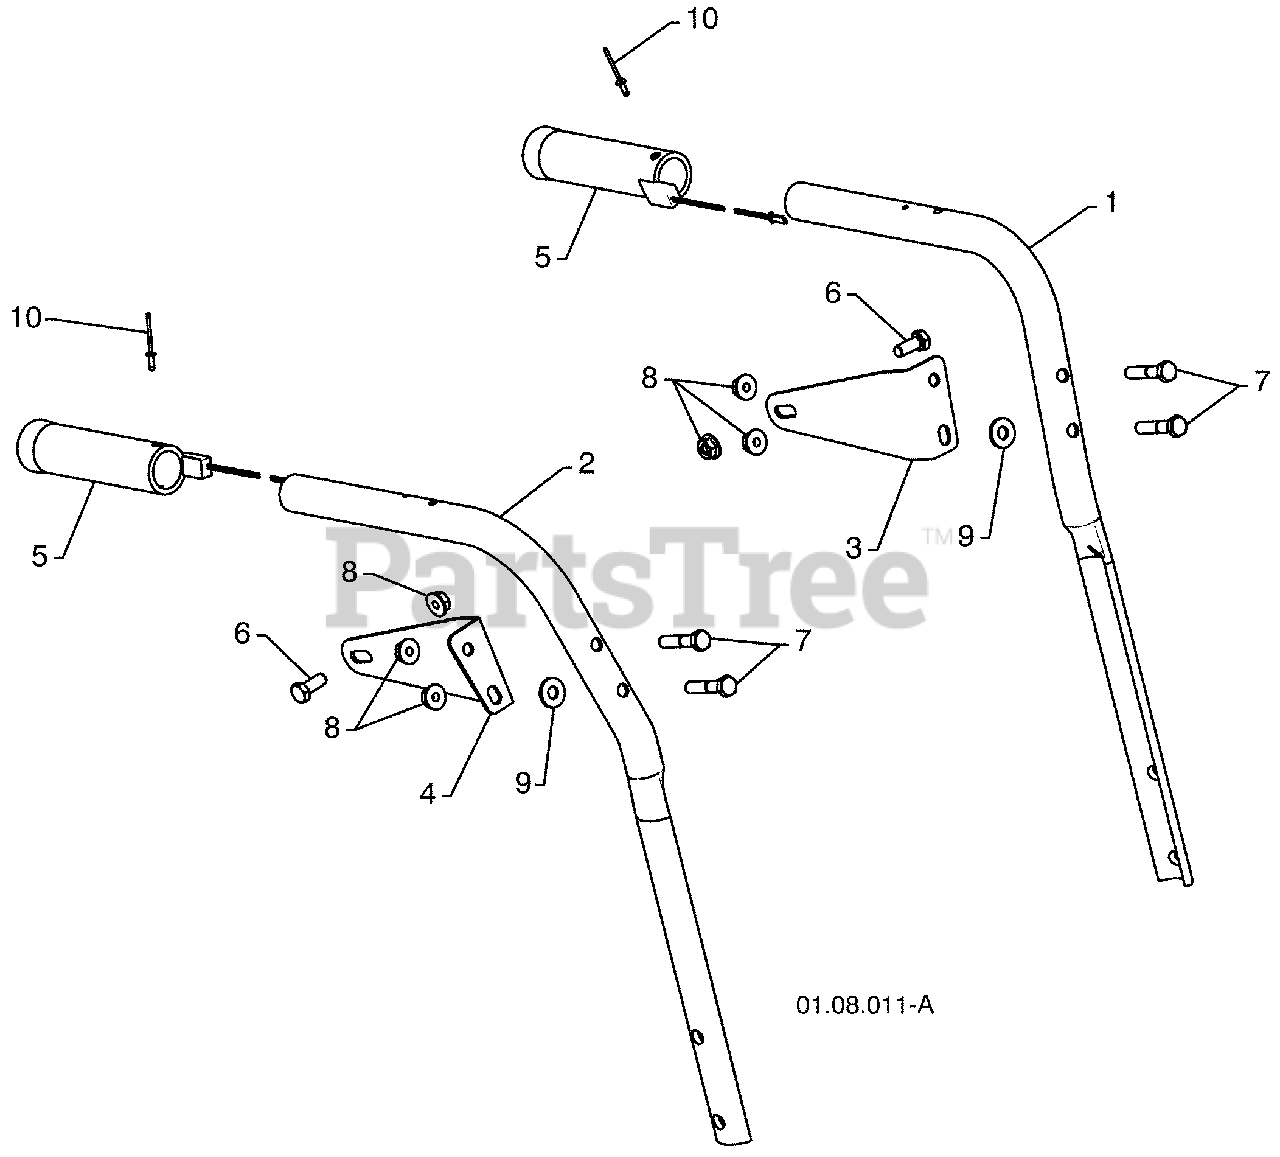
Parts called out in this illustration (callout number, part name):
1	PLOW HANDLE LH
2	PLOW HANDLE RH
3	PANEL BRACKET LH
4	PANEL BRACKET RH
5	HEATED HANDLE GRIP
6	SCREW 5/16-18 X .750
7	SCREW 5/16-18 X 1.50
8	NUT 5/16-18
10	POP RIVET 1/8
